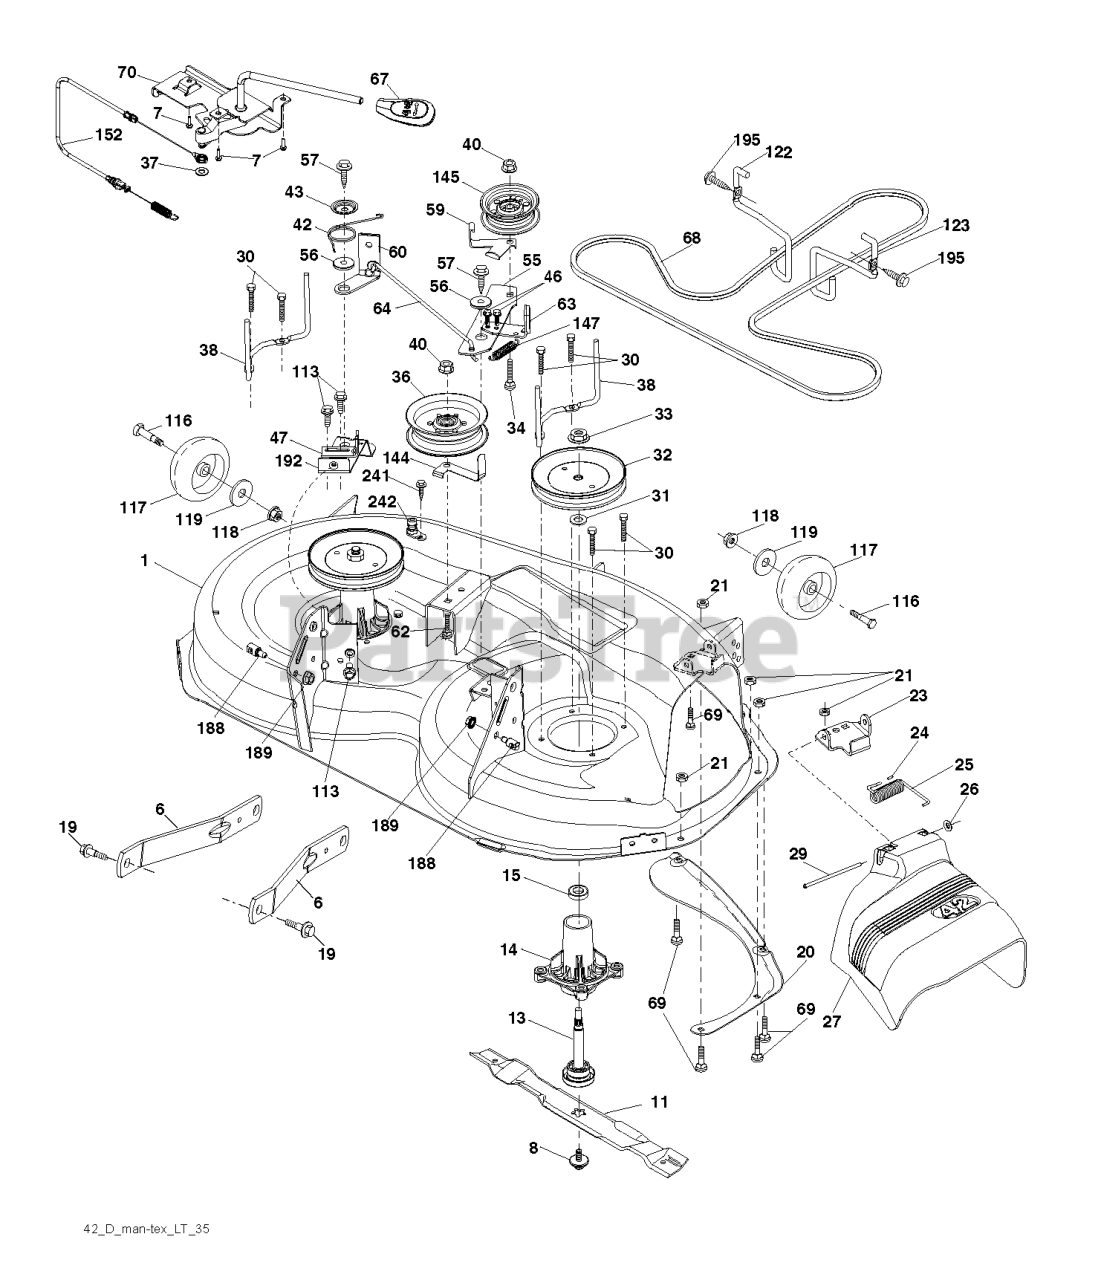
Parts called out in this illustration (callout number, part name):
1	DECK.WELDMENT.42"
6	ARM.SUSPENSION.MOWER.R
7	SCREW.#10 X 0.750.BOS
8	BOLT.WASHER.ASM.7/16-2
11	42" HI-LIFT BLADE
13	SHAFT.ASM.MDRL.N/GREASE.38
14	RP.HOUSING.MANDREL.4PT.
19	BOLT.SHOULDER
20	BAFFLE.VORTEX
21	LOCKNUT
23	BRKT.DEFLECTOR.38"2005+
24	CAP-SLEEVE LT
25	SPRING.TORSION.DEFLECT
26	NUT PUSH M
27	SHIELD.DEFLECTOR.MOWER.42"BLAC
29	ROD.HINGE
30	SCREW, WASHER HEAD
31	WASHER.SPACER.MANDREL
32	PULLEY.MANDREL.5.438.PD
33	NUT.FLANGE.LOCK.TOP
34	BOLT.3/8-16X1.50
36	PULLEY.IDLER.2006
37	WASHER
38	KEEPER.BELT.LH.MANDREL
40	NUT LOCK FLG 3/8-16 UNC
42	SPRING.TORSION.BRAKE
43	SRPING.TORSION.RETAINE
46	SCREW.1/4-20X5/8
47	BRKT.CLUTCH.CABLE
55	IDLER.ARM.42"
56	SPACER.RETAINER
57	SCREW 3/8-16X1
59	GUARD, BELT
60	ARM BRAKE MOWER
63	ARM BRAKE MOWER
64	LINK BRAKE
67	HANDLE.CLUTCH.CABLE.LT
68	BELT.DECK.DRIVE.42"
69	BOLT
70	CLUTCH.ASM.MANUAL.LT.PRED
113	BOLT.5/16HEX.WHS.HD
116	BOLT M
117	WHEEL.GAGE.HALF.SPOKED
118	NUT LOCK FLG 3/8-16 UNC
119	WASHER.5/16.FLAT.STE.STD.
122	KEEPER BELT ENGINE LH
123	KEEPER BELT RH
144	KEEPER.BELT.MOWER
145	PULLEY.IDLER.48"PRIMARY
147	RETURN SPRING
152	CLUTCH CABLE
188	STUD.FASTNER.W/ANTI-ROTATE
189	NUT LOCK HEX FLANGE 5/16-18
192	BRKT.BRAKE.STAND.LH.
195	SCREW, 3/8-16X3/4
241	SCREW.TT.#10-32X.5.3/8.FLANGE
242	PORT.WASHOUT
